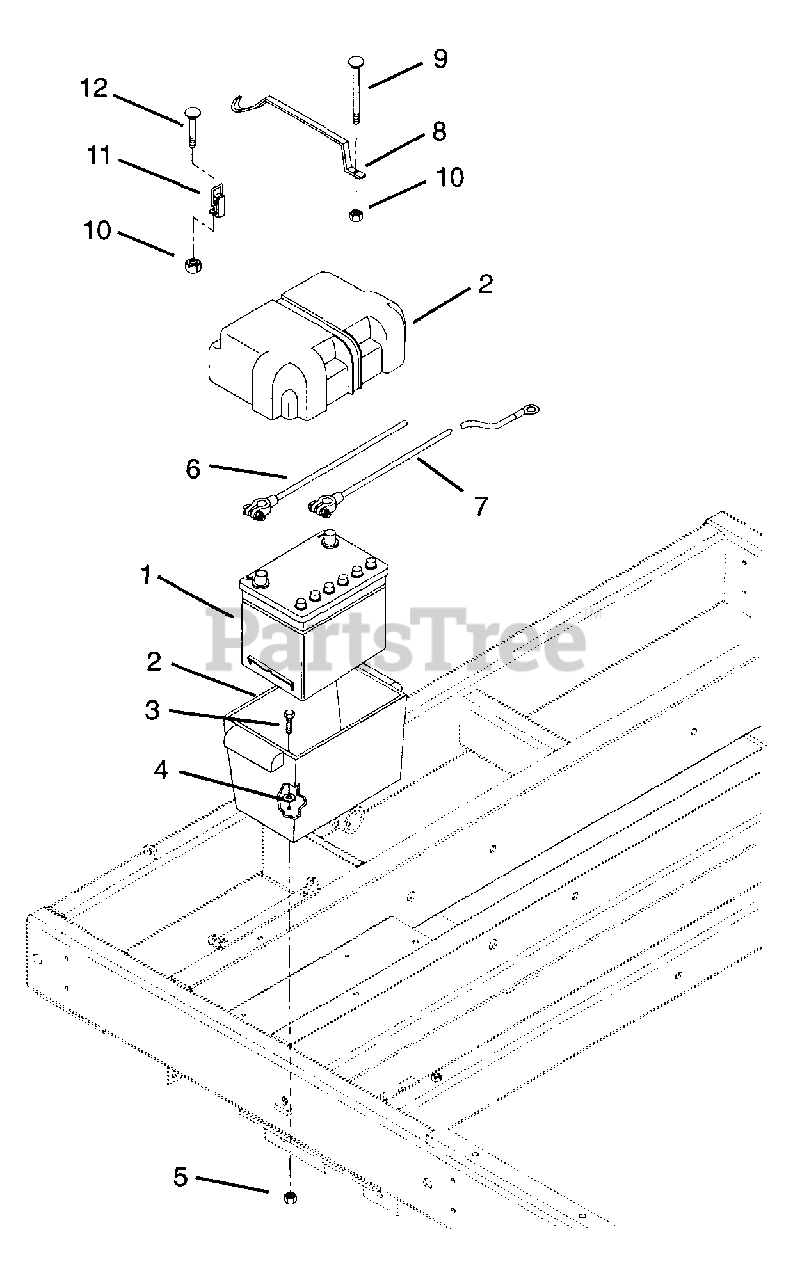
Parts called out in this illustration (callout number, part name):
2	Battery Box
3	Bolt-Hex .25-20 x .75 Grade 5
4	Washer-Flat-Steel .312 x .734 x .065
5	Nut-Locking-Center .25-20
6	Battery Cable
6	Cable-Battery Positive
7	Cable-Negative Battery
8	Strap-Battery Hold Down
9	Bolt-Round Head Square Neck .31-18 x 6.50
10	Nut-Locking-Center .31-18
11	Latch Assembly-Battery Hold Down
12	Bolt-Round Head Square Neck .31-18 x 2.50
